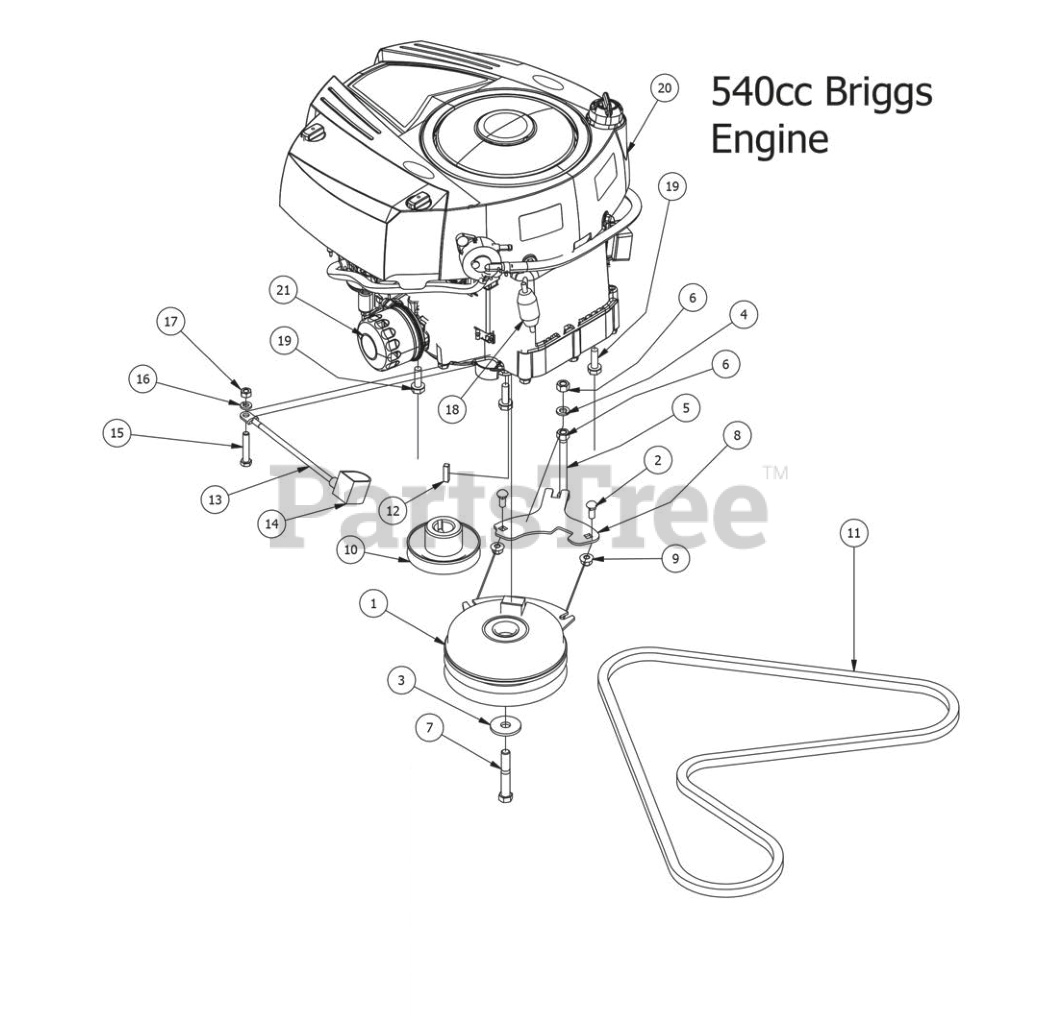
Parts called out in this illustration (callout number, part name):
1	MZ Clutch Assembly
2	5/16-18x3/4 carriage bolt
3	1/2 Belleville Washer
4	3/8" Lock Washer
5	3/8-16x3-1/2 grade 5 hex bolt
6	3/8" Hex Nut
7	7/16x2 3/4 Fine Thread Bolt
8	MZ Clutch Holder
9	5/16" Nylon Flange Nut
10	3-3/4" Motor Pulley
12	1/4" x 1" Key
13	Ground Cable
14	Black Boot For ground cable
15	5/16" x 1 3/4" Hex Bolt
16	5/16" Lock Washer
18	Universal inline Fuel Filter
19	3/8 x 1 1/8 bolt
20	540cc Briggs Intek Engine-MZ
21	Briggs Oil Filter
